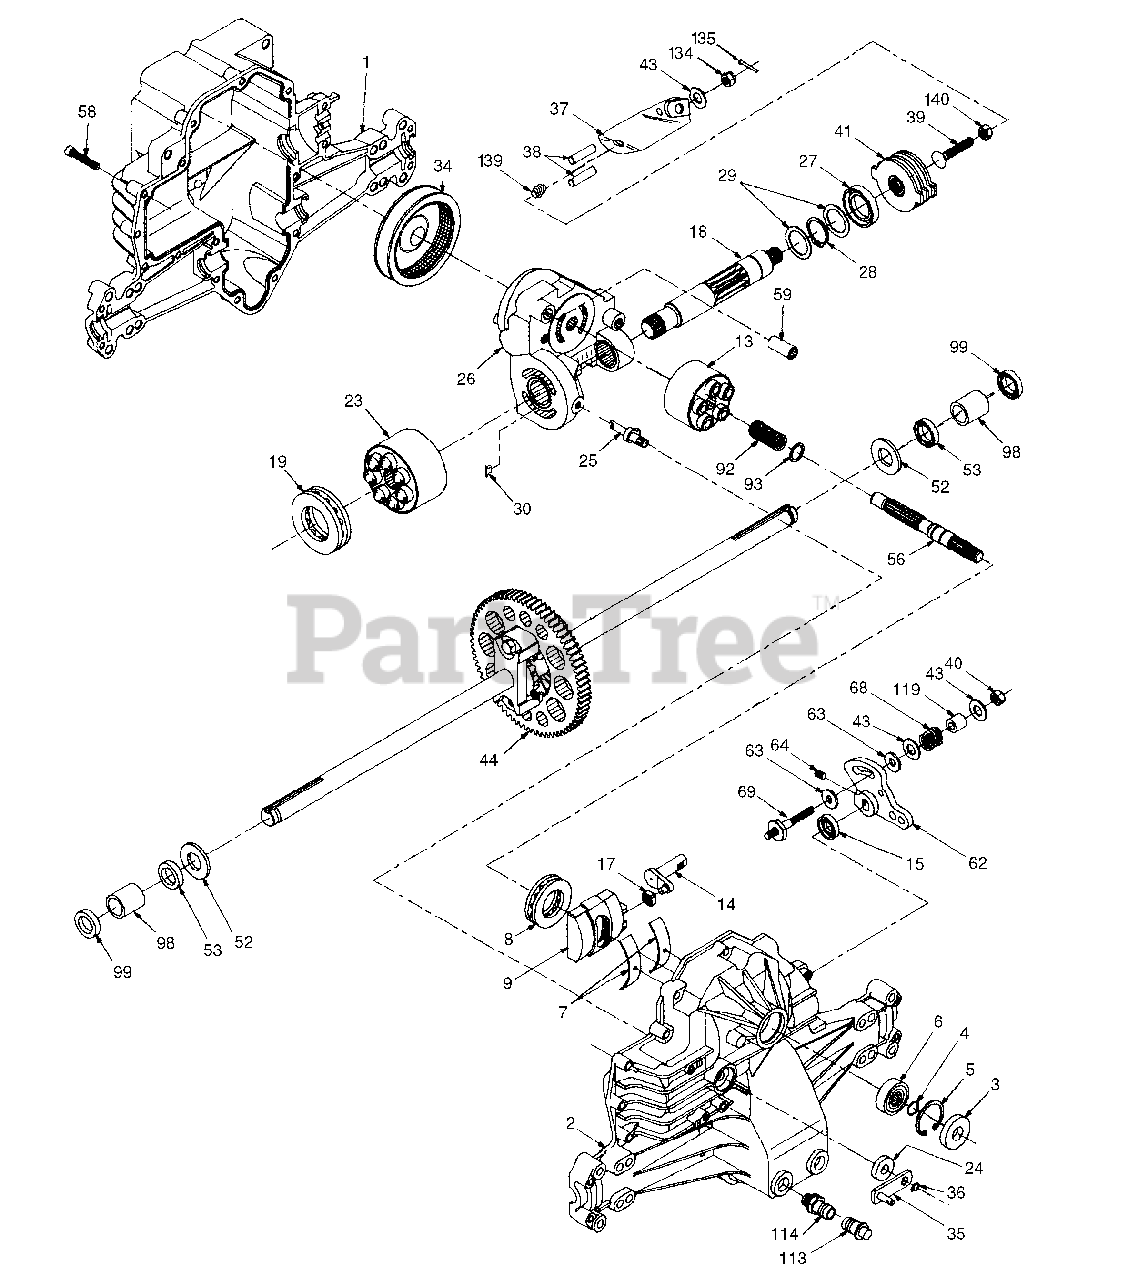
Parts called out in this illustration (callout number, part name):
1	Housing, Lower
2	Assembly, Upper Housing
3	Seal, Lip
4	Ring, Wire Retaining
5	Ring, Retaining
6	Bearing, Shaft Ball
7	Bearing, Cradle
8	Bearing, Thrust 30 x 52 x 13
9	Swashplate, Variable
13	Block, Cylinder Assembly
14	Arm, Trunnion
15	Seal, Lip
17	Guide, Slot
18	Shaft, Motor
19	Bearing, Thrust 42 x 68 x 16
23	Block, Cylinder Assembly
24	Seal, Lip 10 x 25 x 7
25	Actuator, Bypass
26	Center Section Assembly Kit
27	Seal, Lip 26 x 42 x 8
28	Ring, Retaining
29	Washer 26 x 35 x 1
30	Nut, Jam
34	Oil Filter Element
35	Arm, Bypass
36	Ring, Retaining
37	Arm, Actuating
38	Pin, Actuating
39	Bolt 5/16-24 x 1-3/4
40	Locknut, Hex 5/16-24 UNJC
41	Brake Rotor/Stator Kit
43	Washer 7/16 x 7/8 x .060
44	Differential Assembly
52	Washer 3/4 x 1.5 x .13
53	Seal .75 x 1.25 x .250
56	Shaft, Input
58	Bolt 1/4-20 x 1.38
59	Pin .5 OD x .43 ID x .750
62	Arm, Control
63	Puck, Dampener
64	Set Screw
68	Spring
69	Stud 5/16-24
92	Spring, Block
93	Washer, Block Thrust
98	Sleeve Bearing
99	Seal, Wiper
113	Cap, Vent Assembly
114	Fitting, O-Ring Assembly
119	Spacer
134	Nut, Castle 5/16-24
135	Pin, Cotter
139	Spring, Compression
140	Nut, Hex 5/16-24
